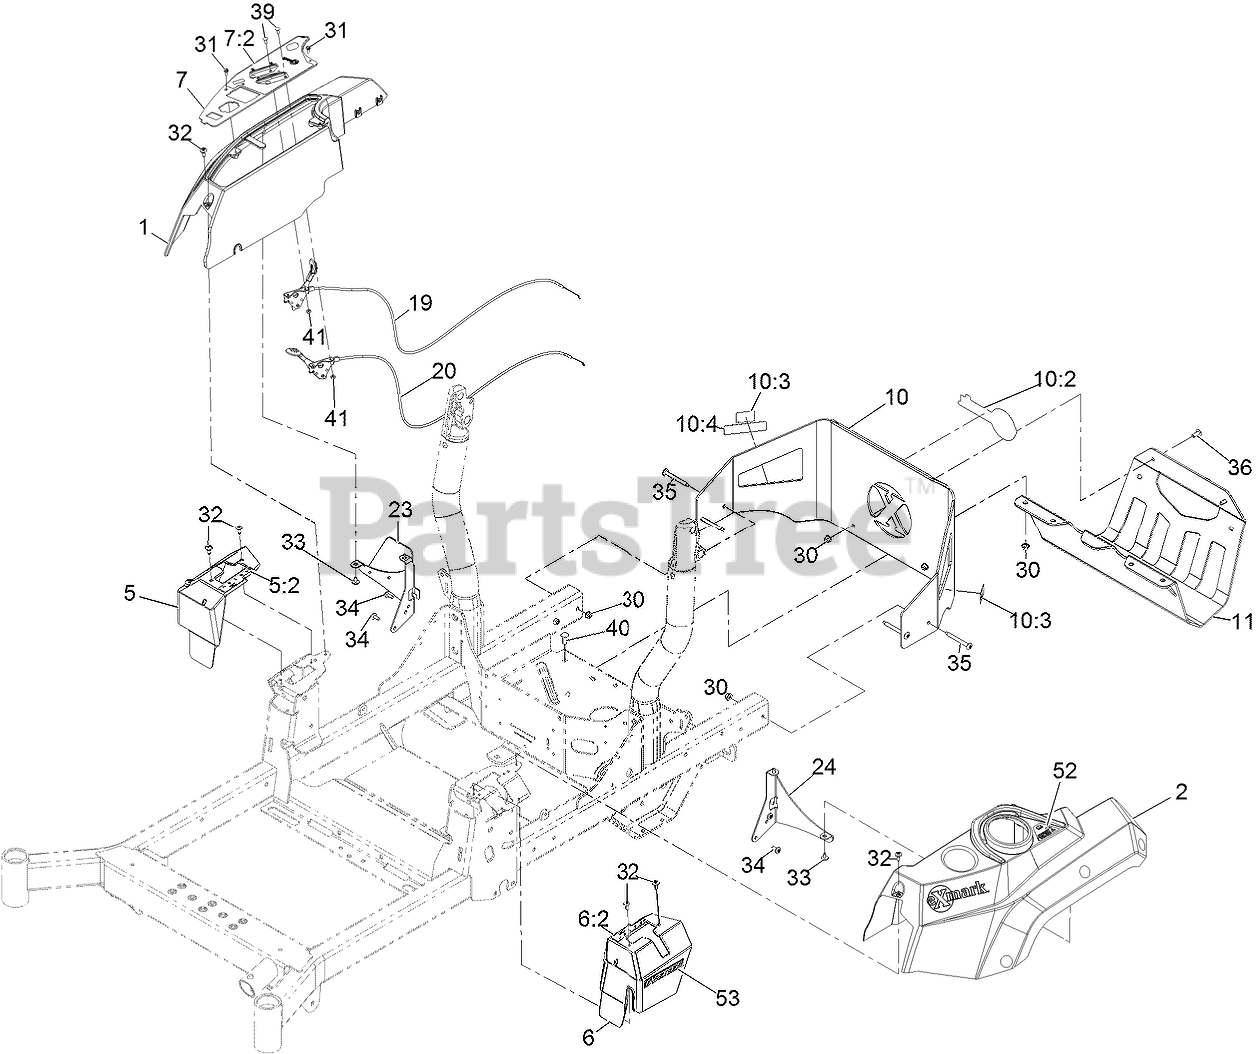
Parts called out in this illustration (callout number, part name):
1	CONSOLE, RH
2	CONSOLE, LH
5	COVER-CONTROL, MOTION (RH
5:2	Decal-Control, Motion (RH)
6	COVER-CONTROL, MOTION (LH
6:2	Decal-Control, Motion (LH)
7	ASM-CONTROL PANEL W/EXMARK DECAL
7:2	DECAL-CONTROL PANEL
10	REAR GUARD ASM
10:2	DECAL, EXMARK LOGO
10:3	DECAL-WARNING
10:4	DECAL-ARRESTOR, SPARK
11	Guard-Muffler [black]
19	CABLE-CONTROL, CHOKE
20	CABLE-CONTROL, THROTTLE
23	SUPPORT-CONSOLE, RH
24	BRACKET-CONSOLE, LH
30	NUT-HF, NI
31	SCREW-HWH
32	SCREW-SHOULDER
33	SCREW-TORX
34	SCREW-TORX
35	SCREW-TORX
36	SCREW-TORX
39	BOLT-CARR
40	SCREW-CARR
41	NUT-LOCK, NI
52	DECAL-FILL, FUEL
53	DECAL-E-SERIES
